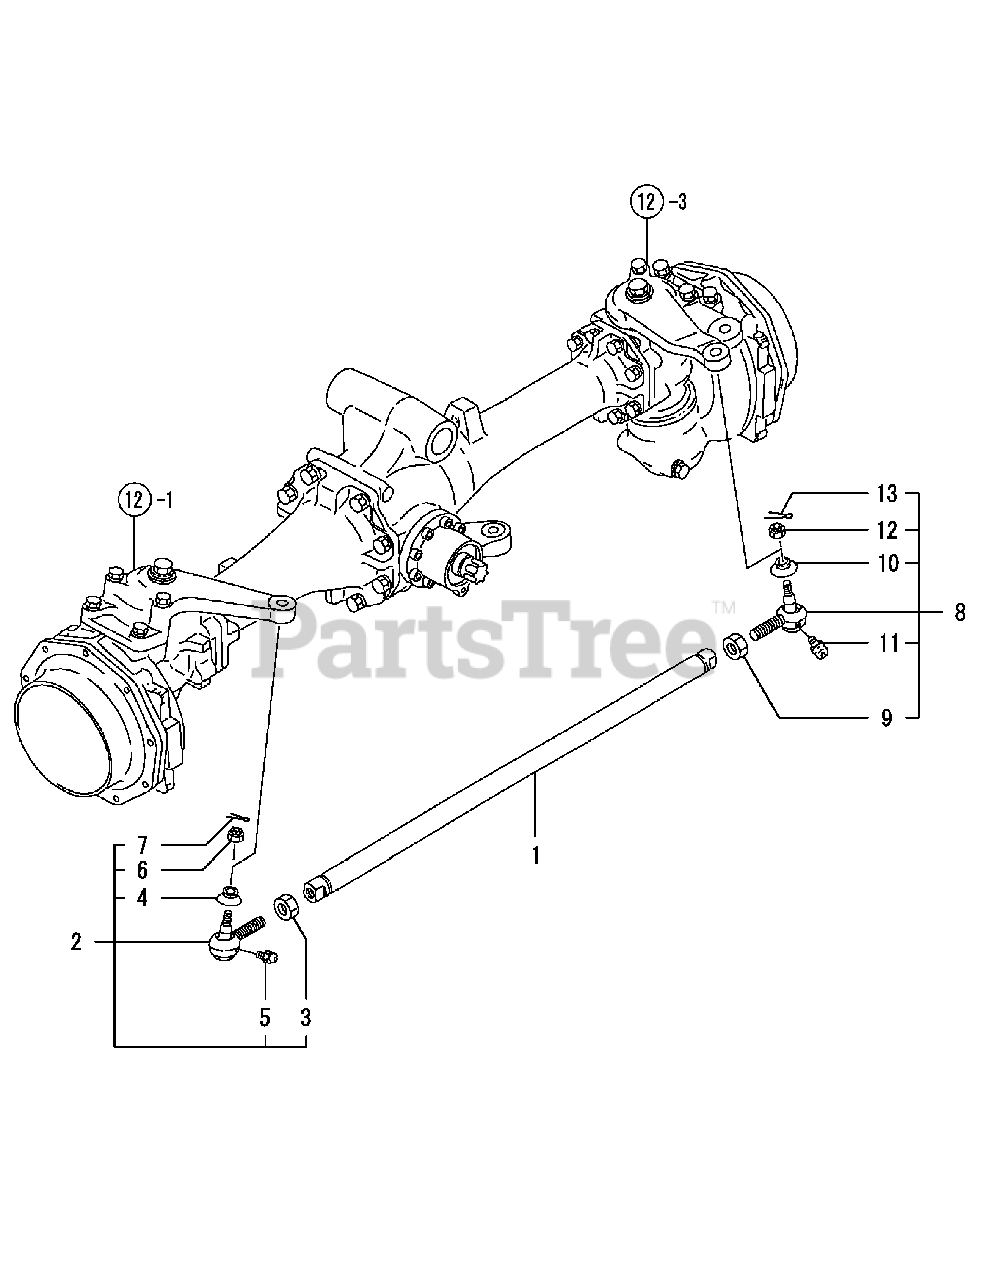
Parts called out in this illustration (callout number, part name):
2	TIRE-ROD END KIT(LR)
5	NIPPLE MT6X1, GREASE
7	COTTER PIN 3.0X 25
8	TIRE-ROD END KIT RL
11	NIPPLE MT6X1, GREASE
13	COTTER PIN 3.0X 25
